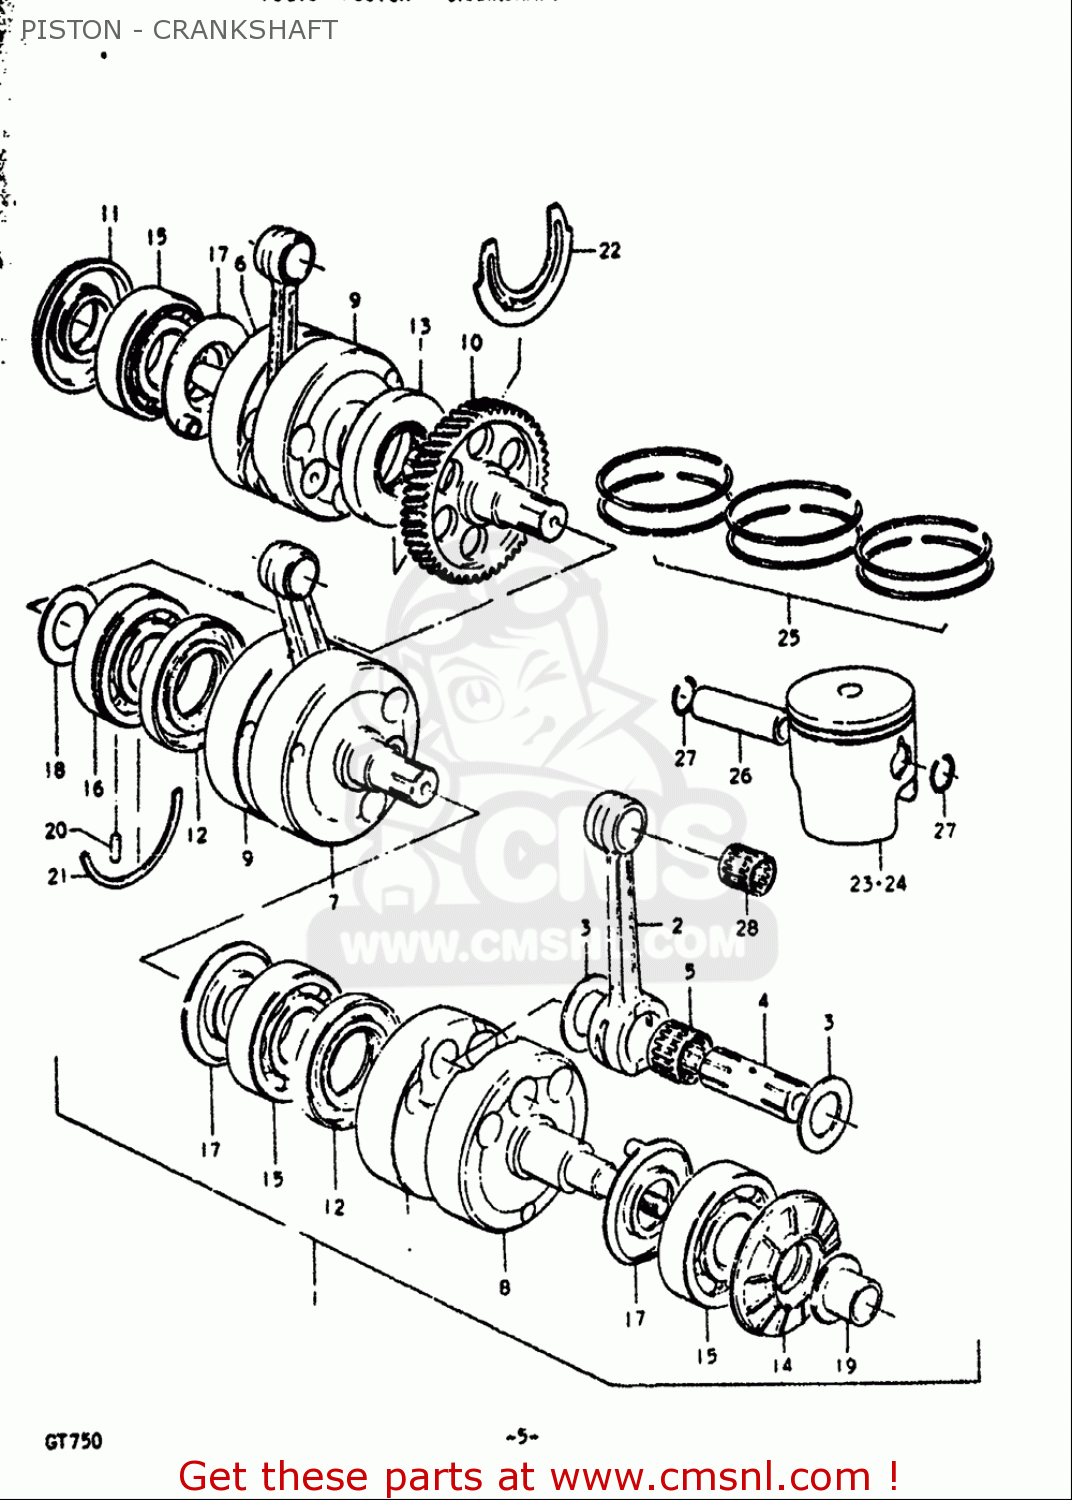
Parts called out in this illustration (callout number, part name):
3	WASHER
4	PIN,CRANK
5	BEARING(24X30X20)
11	SEAL,OIL(25X78X8)
12	SEAL,OIL(38X78X9.5)
13	SEAL,OIL(38X78X9)
14	SEAL,OIL(30X78X8)
15	BEARING(30X78X19)
20	ROLLER(4X13.8)
21	C-RING
23	PISTON,R
24	PISTON,L
25	RING SET,PISTON
26	PIN,PISTON (18MM)
27	CIRCLIP,PISTON PIN
28	BEARING(18X23X24)
